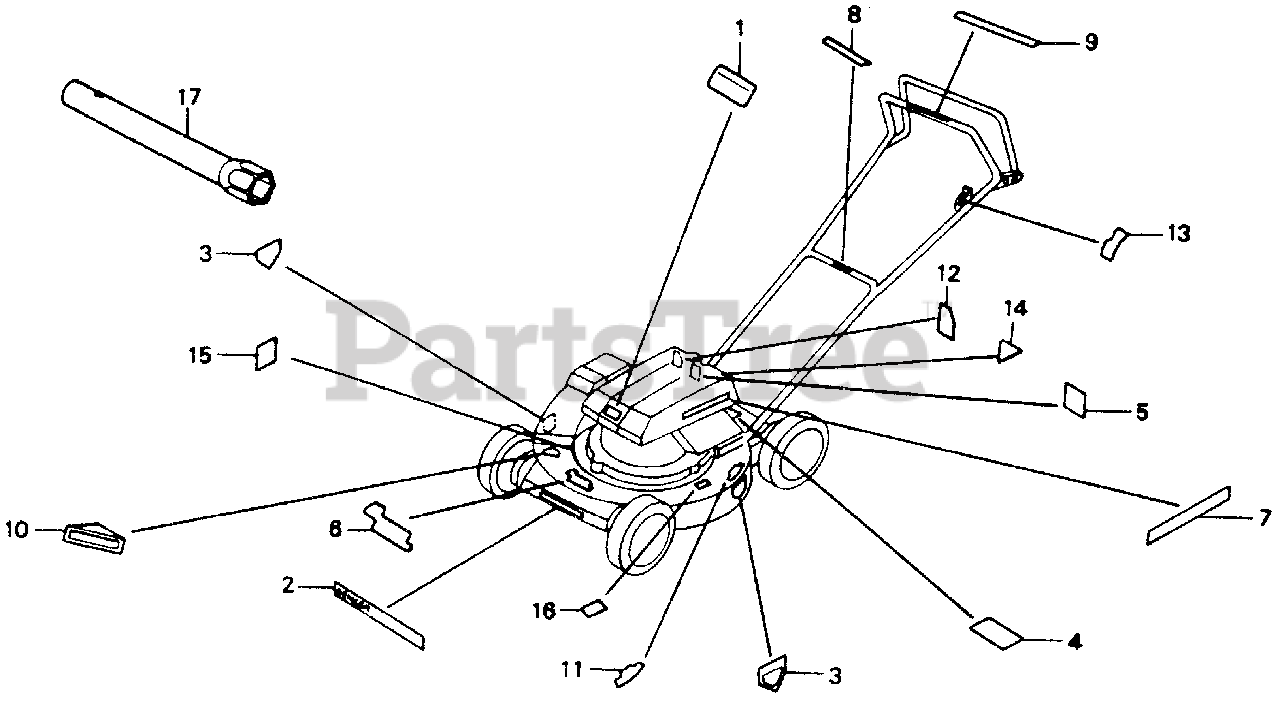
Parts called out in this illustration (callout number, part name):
1	EMBLEM (NOT AVAILABLE)
2	LABEL A, HOUSING CAUTION (ENGLISH)
3	LABEL B, HOUSING CAUTION (ENGLISH)
4	CAUTION, OPERATOR
5	CAUTION, FUEL
7	MARK, EASY START
8	CAUTION, START (NOT AVAILABLE)
9	MARK, BLADE CONTROL
10	CAUTION, ADAPTER
11	LABEL, PLUG CAUTION (ENGLISH)
12	MARK, AIR CLEANER CAUTION
13	MARK, THROTTLE
15	MARK, OIL CAUTION (NOT AVAILABLE)
17	WRENCH, BOX (P21)
